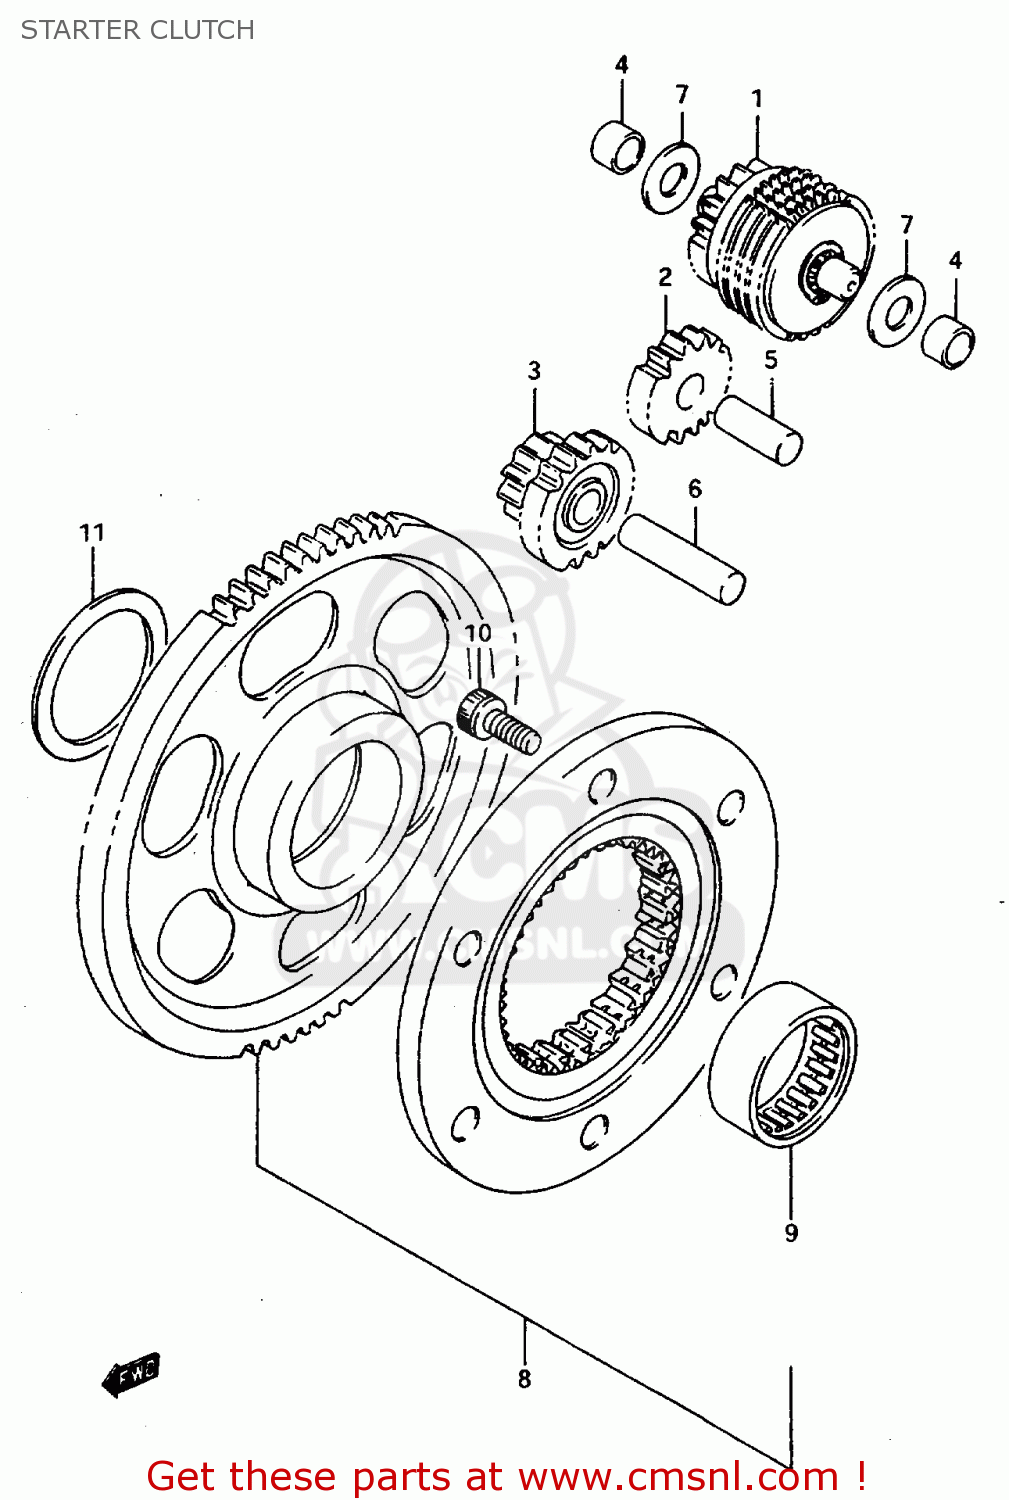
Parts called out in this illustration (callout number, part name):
1	LIMITER ASSY,S
2	GEAR,STARTER IDLE NO.2
3	GEAR,STARTER IDLE NO.3
4	BUSH,LIMITER GEAR SHAFT
5	PIN
6	PIN
7	WASHER
8	CLUTCH SET,STARTER
9	BEARING(35X43X18)
10	BOLT
11	WASHER
